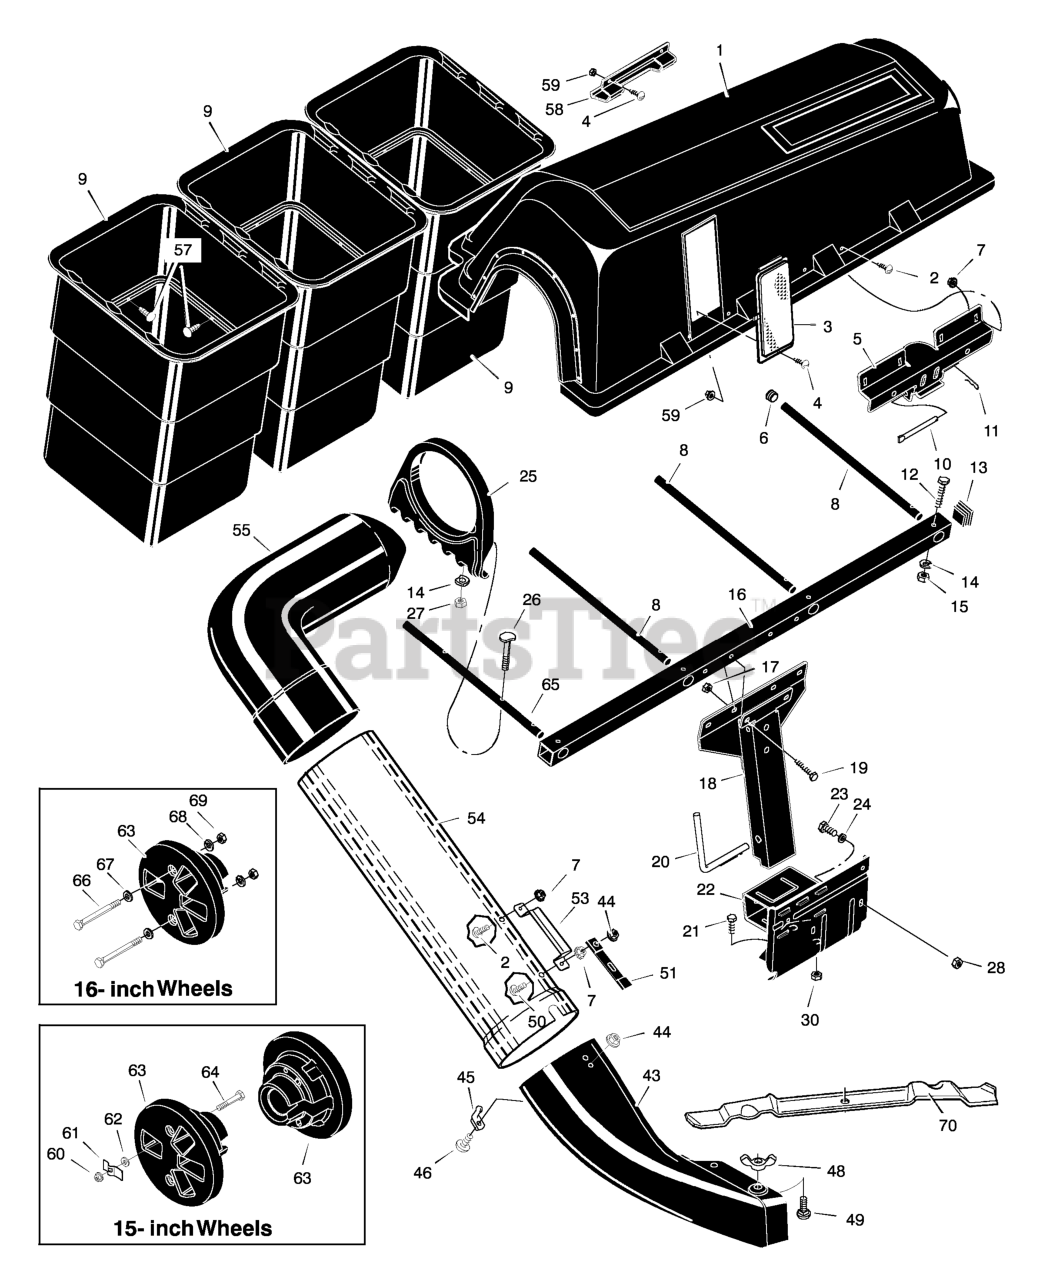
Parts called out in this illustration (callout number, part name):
1	Cover, Bagger
5	Hinge, Bracket
7	Nut, Hex
8	Tube, Container
9	Container
10	Pin, Cover Hinge
11	Pin, Hair
13	Plug
14	Lockwasher
16	Tube, Support
17	Nut
18	Assembly, Channel
20	Pin, Channel Mount
21	Bolt, Hex
22	Assembly, Bagger Mount
23	Bolt, Hex
25	Holder, Elbow
27	Washer
28	Nut, Super Flange
30	Nut, Hex
43	Tube, Extension
44	Locknut, Flange
45	Pin, Latch
46	Bolt, Carriage
48	Wingnut
49	Bolt, Carriage
51	Latch, Rubber
53	HANDLE, Connect Tube
54	Tube, Connecting
57	Fastener, Panel
58	Handle, Plastic
59	Nut, Hex
60	Nut, Flange
61	Clip, Wheel
62	Retainer
63	Weight, Wheel
65	Tube, Right Container
68	Washer
70	Blade, High Lift
